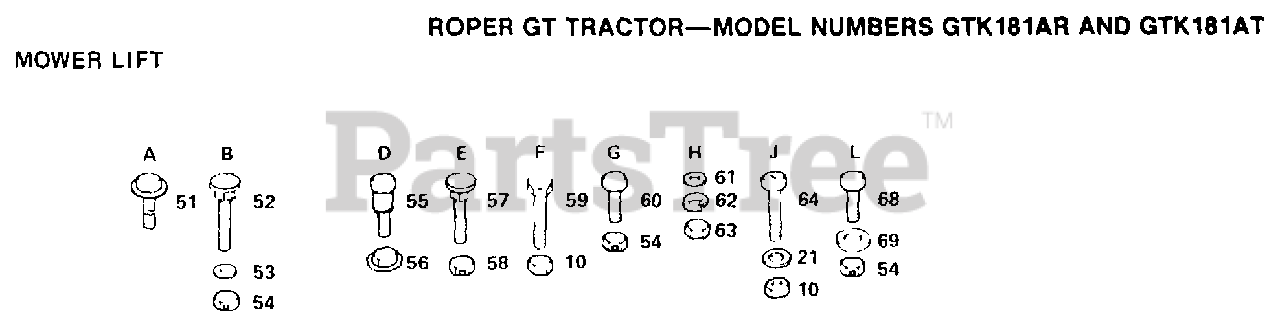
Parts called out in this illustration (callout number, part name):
21	WASHER
51	SCREW LT
52	BOLT
53	WASHER
55	SHOULDER BOLT T
56	NUT T
57	BOLT
58	LOCKNUT
59	BOLT
61	WASHER PM
68	BOLT
69	WASHER M
